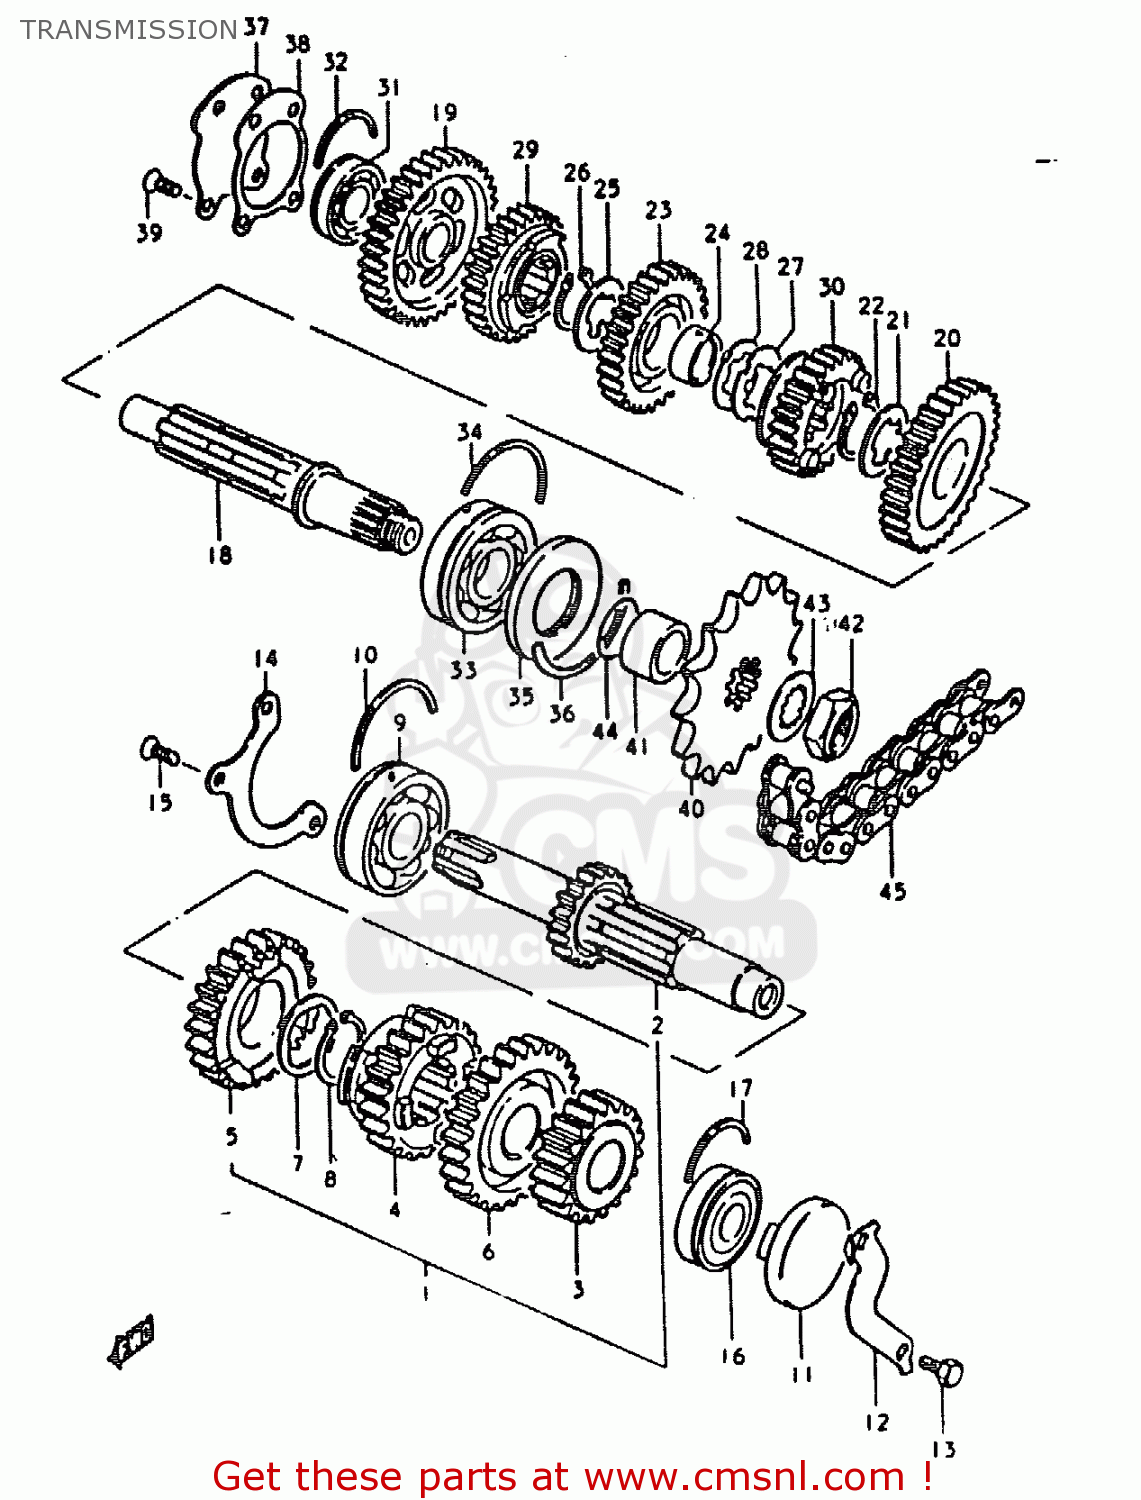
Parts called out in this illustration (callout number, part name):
1	SHAFT,COUNTER
2	SHAFT,COUNTER
3	GEAR,SECOND DRIVE
4	GEAR,THIRD DRIVE
5	GEAR,FOURTH DRIVE
6	GEAR, 5TH DRIVE
7	WASHER,LOCK
8	CIRCLIP
9	BEARING(25X62X17)
10	C-RING
11	PLUG
12	RETAINER,CL PUSH ROD OIL SEAL
13	BOLT
14	RETAINER,CNTR SHAFT BEARING
15	SCREW
16	BEARING(20X47X14)
17	C RING
18	SHAFT,DRIVE
19	GEAR,FIRST DRIVEN
20	GEAR,SECOND DRIVEN
21	WASHER,LOCK
22	CIRCLIP
23	GEAR,THIRD DRIVEN
24	BUSH,3RD DRIVEN GEAR
25	WASHER,LOCK
26	CIRCLIP
27	WASHER,LOCK
28	WASHER
29	GEAR,FOURTH DRIVEN
30	GEAR,FIFTH DRIVEN
31	BEARING
32	C RING
33	BEARING(25X62X17)
34	C-RING
35	SEAL,OIL(32X62X7)
36	C RING
37	PLATE,DRIVE SHAFT
38	GASKET,DRIVESHAFT PLATE (MCA)
39	SCREW
40	SPROCKET,ENGINE
41	SPACER(25X32X18.6)
42	NUT
43	WASHER
44	O RING(D:1,ID:24.5)
45	CHAIN ASSEMBLY,DRIVE
